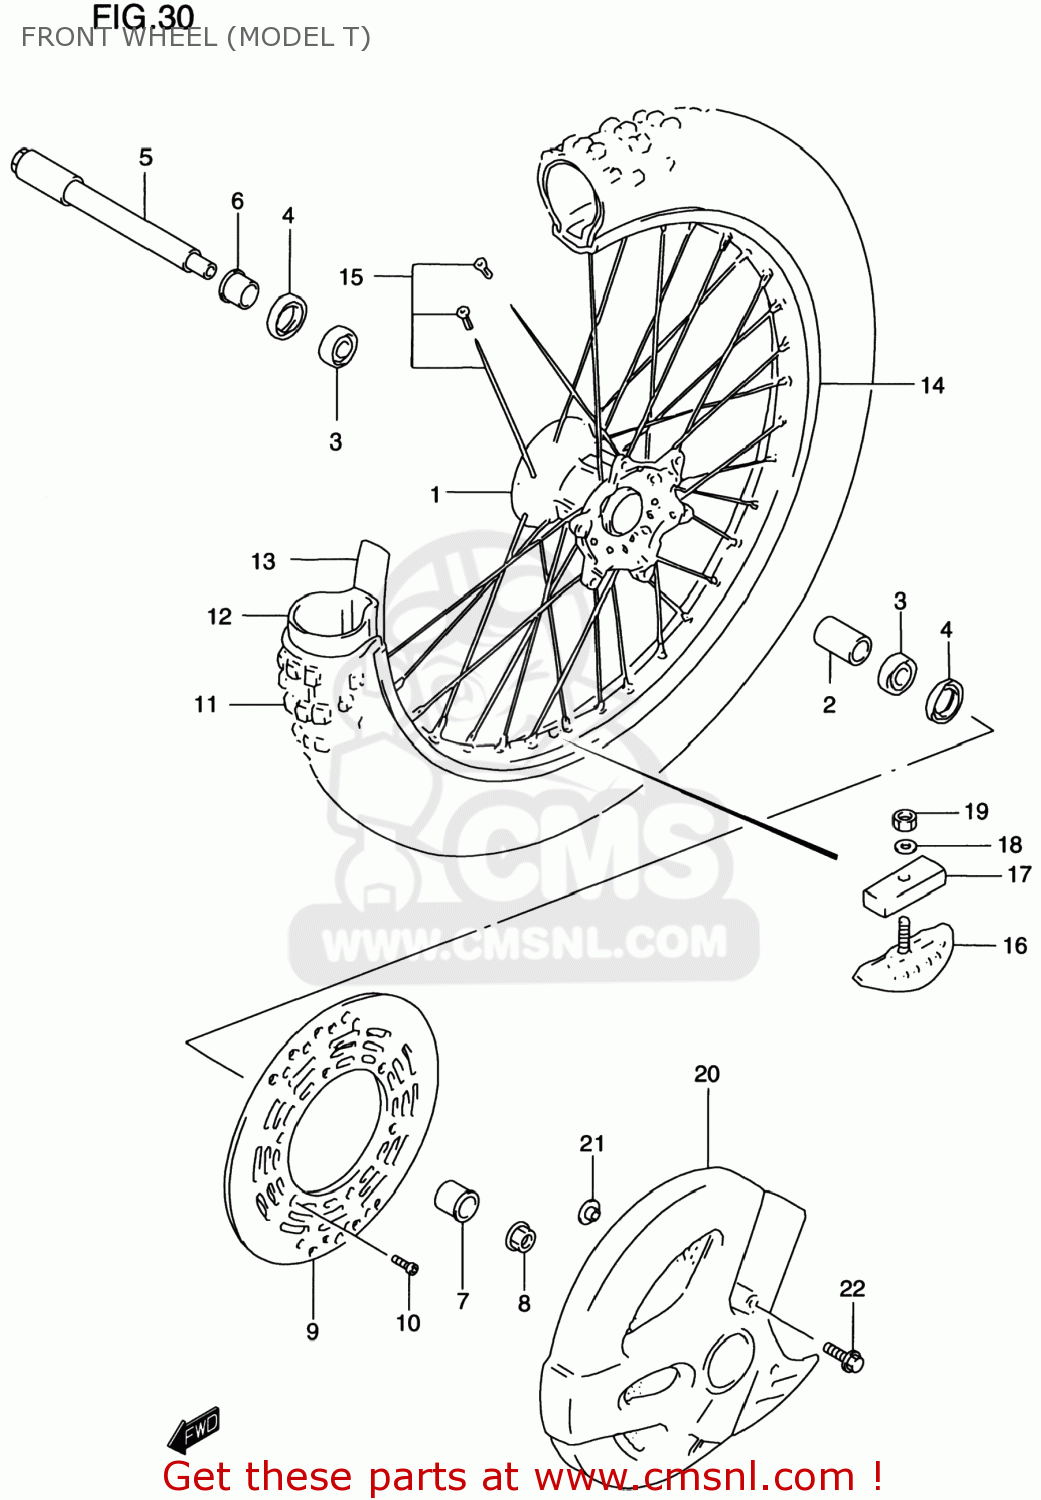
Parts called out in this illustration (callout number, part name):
1	HUB,FR WHEEL
2	SPACER,FR HUB BEARING
3	BEARING
4	SEAL,OIL(25X37X6)
5	AXLE,FRONT
6	SPACER,FRONT AXLE,RIGHT
7	SPACER,FR AXLE,L
8	NUT
9	DISC,FR BRAKE
10	SCREW
11	TIRE,FRONT 80/100-21
12	TUBE
13	PROTECTOR,WHEEL INNER
14	RIM,FRONT WHEEL (1.60X2
15	SPOKE SET,FR WHEEL
16	STOPPER,BEAD
17	CUSHION,BEAD STOPPER
18	WASHER
19	NUT
20	COVER,FRONT BRAKE DISC
21	WASHER
22	BOLT(6X16)
